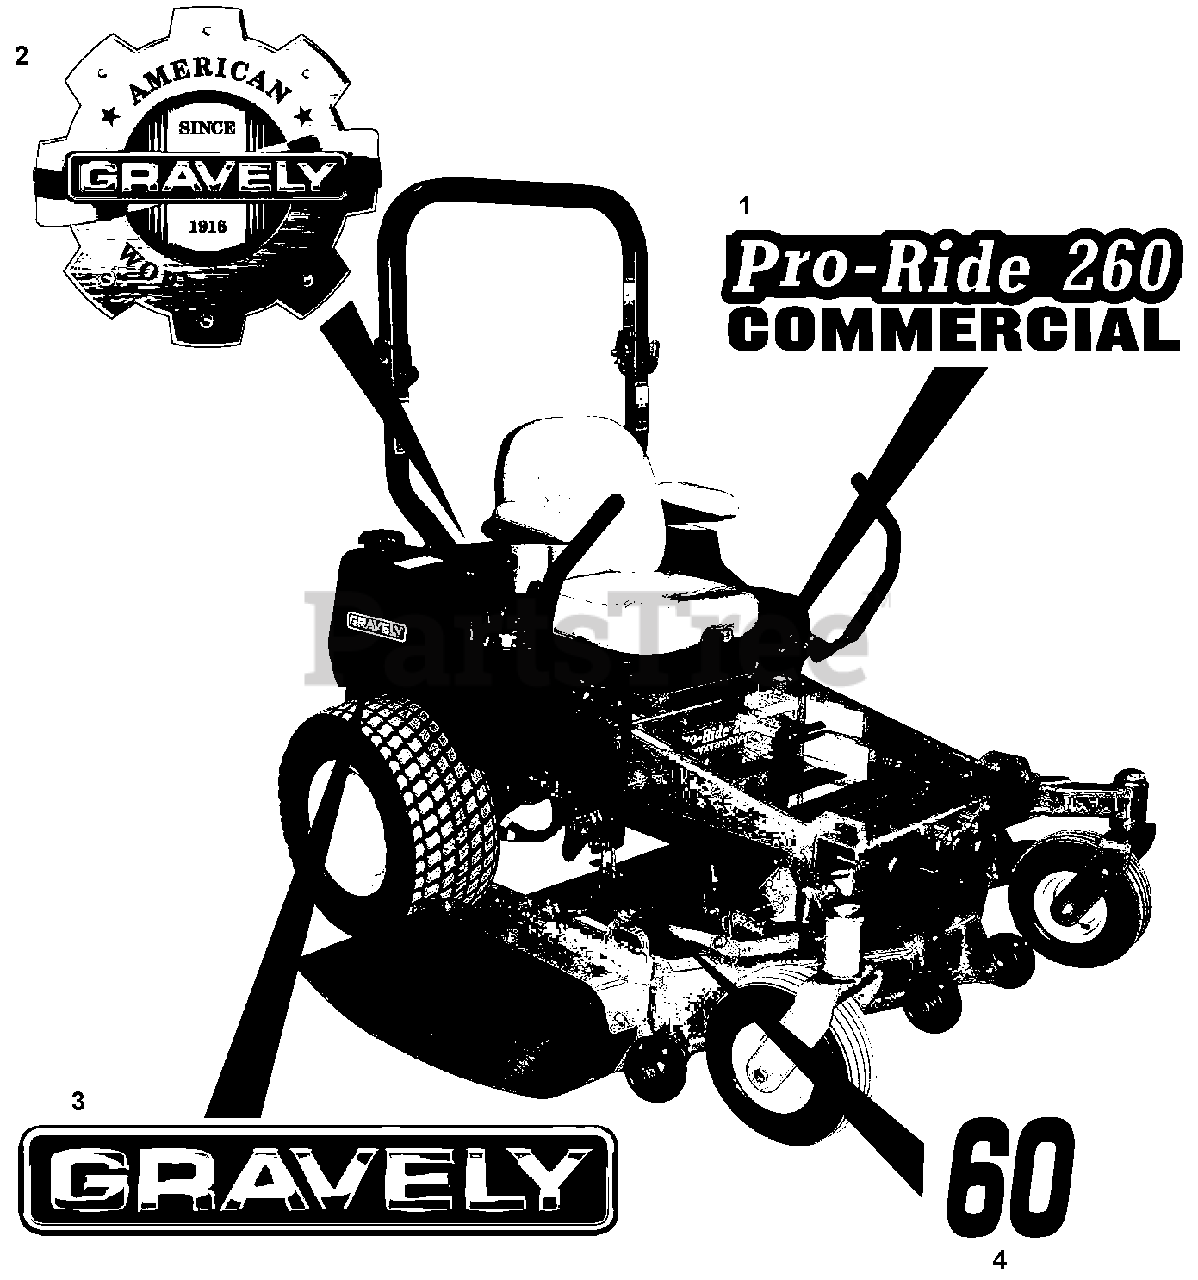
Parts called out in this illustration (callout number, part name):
1	Decal, Pro-Ride 254 (992220)
2	Decal, Gravely Heritage, Large
3	Decal, 9.5" Gravely (Serials 101 – 2499)
4	Decal, Deck Size 54" (992220)
